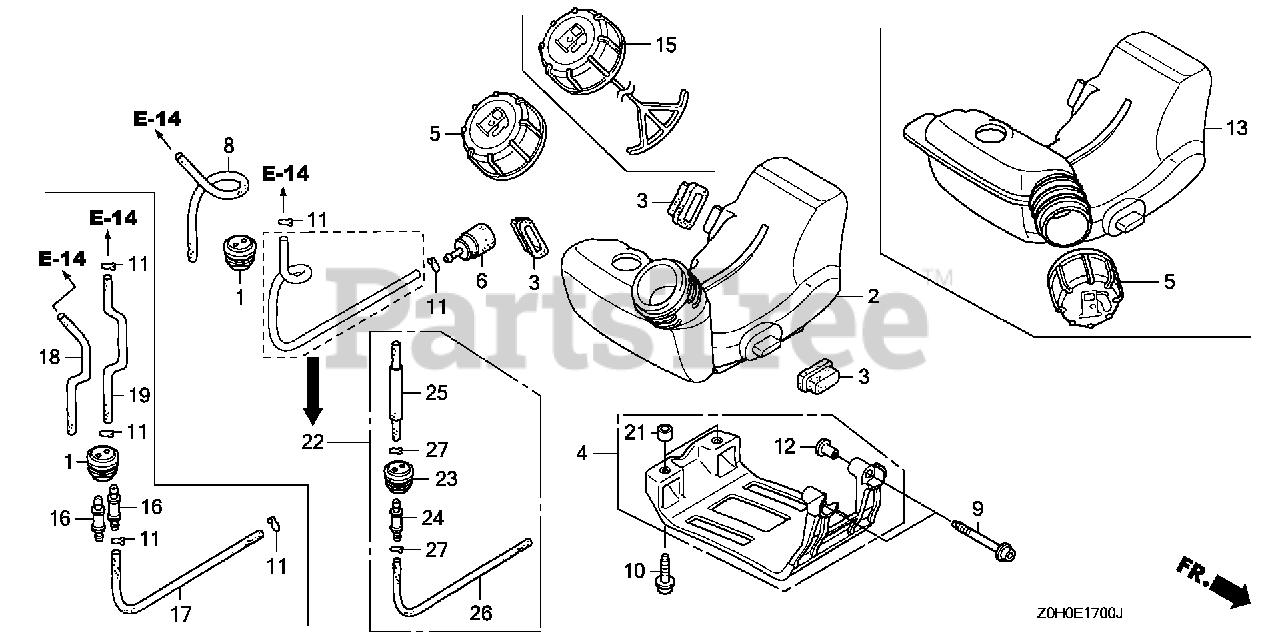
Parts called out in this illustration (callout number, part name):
1	GROMMET, FUEL TUBE
3	RUBBER, TANK MOUNTING
5	CAP ASSY., FUEL TANK
6	FILTER, FUEL
8	TUBE, FUEL RETURN
11	CLIP, TUBE
13	TANK, FUEL
22	GROMMET ASSY., FUEL TANK
23	GROMMET, FUEL TUBE
24	FITTING
25	TUBE, FUEL FEED
26	TUBE A, FUEL
27	CLIP, TUBE
